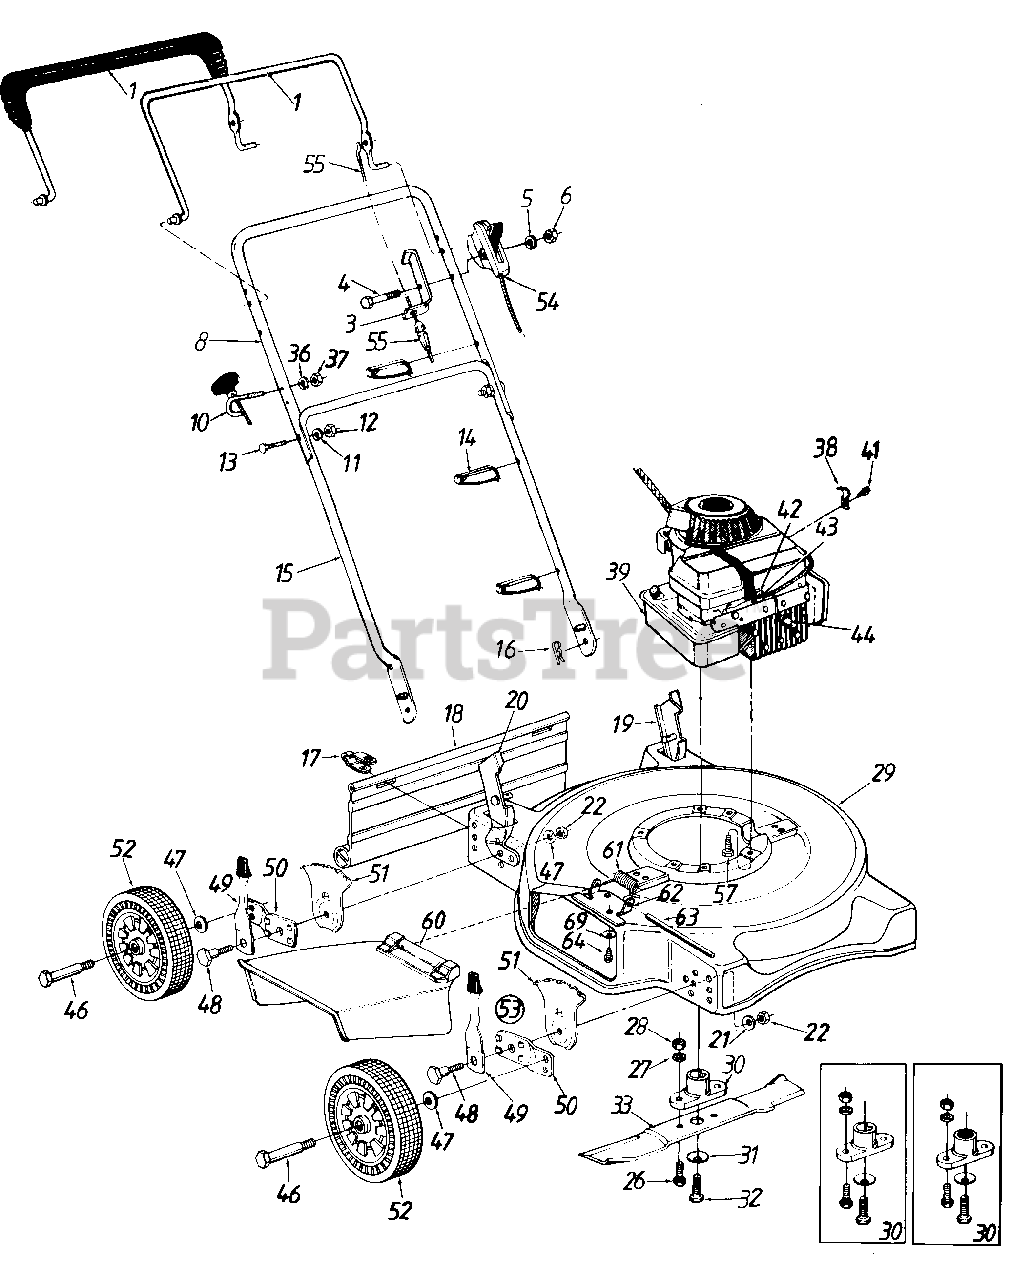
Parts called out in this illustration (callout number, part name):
1	Control Handle Ass'y.
3	Cable Brkt.
4	Hex Bolt 1/4-20 x 1.75" Lg.
5	Spr. Wash. 1/4" I.D.
6	Hex Nut 1/4-20 Thd.
8	Upper Handle
10	Rope Guide
11	L-Wash. 5/16" I.D.
12	Hex Nut 5/16-18 Thd.
13	Curved Carriage Bolt 5/16-18 x 1.38" Lg.
14	Cable Tie
15	Lower Handle
16	Hairpin Cotter
17	Hinge Clip
18	Rear Flap
19	Handle Bracket Ass'y.-L.H.
20	Handle Bracket Ass'y.-R.H.
21	Bell-Wash. .39" I.D. x 1.38"
22	Hex Nut 3/8-16 Thd.
26	Hex Bolt 3/8-24 x 1" Lg.
27	L-Wash. 3/8" I.D.
28	Hex Nut 3/8-24 Thd.
30	Blade Adapter Kit (Keyed)
31	Bell-Wash. .39" I.D.
32	Hex Bolt 3/8-24 x 1.5" Lg.
33	20" Blade
36	L-Wash. 1/4" I.D.
37	Hex Nut 1/4-20 Thd.
38	Cable Clampt
39	Engine
41	Hex B-Tap Scr. #10 x .38"
42	Cable Clamp
43	Hex AB-Tap Scr. #8 x .38"
44	Spark Plug Boot
46	Axle Bolt
47	Bell-Wash. .400" I.D. x .88"
48	Shld. Bolt .50" Dia. x .357"
49	Spring Lever Ass'y. w/Knob
51	Height Adj. Plate
52	Wheel Ass'y. Comp.
53	Height Adj. Ass'y. Comp.-R.F. & L.R.
54	Throttle Control Ass'y. Comp.- 51 .62"
55	Control Cable-36"
57	Hex L-Wash. Hd. Scr. 3/8-16 x 1.0" Lg.
60	Chute Deflector Ass'y.
61	Torsion Spring
62	Adapter Plate
63	Hinge Pin
64	Hex Self-Tap Scr. 1/4-20 x .5" Lg.
